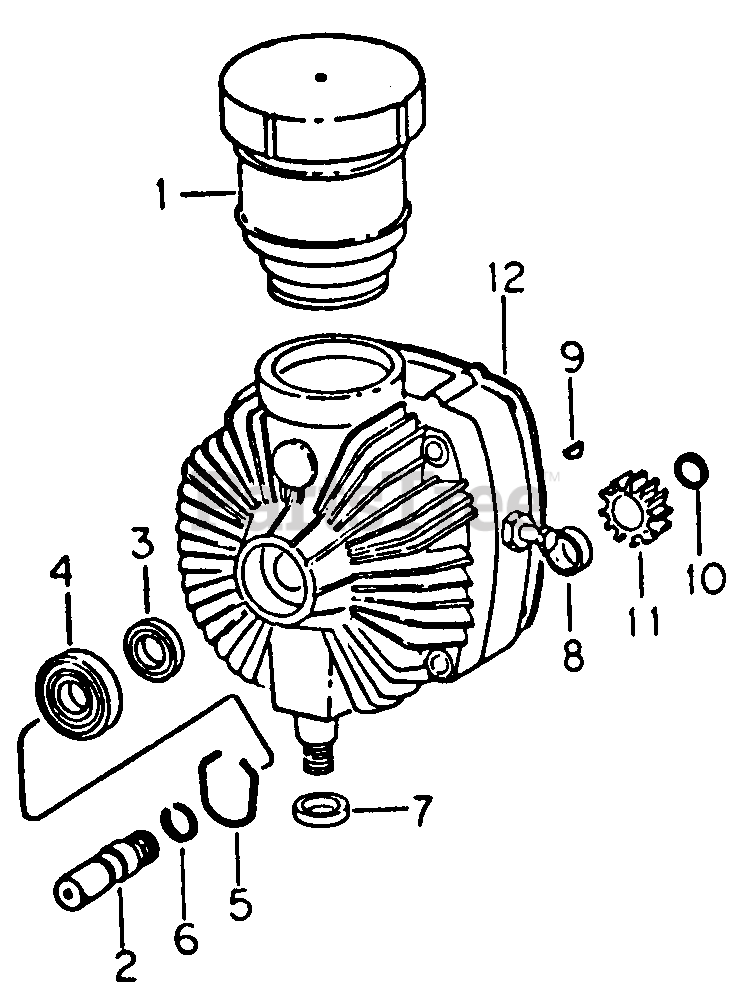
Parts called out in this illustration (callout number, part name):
1	Kit, Reservoir Service
3	Seal, Oil
4	Bearing Assy, Ball
7	Seal, Oil
9	Key, 1/8 X 1/2 SAE 3 Woodruff
10	Ring, Retaining
12	Gasket, Hydrostatic Drive
